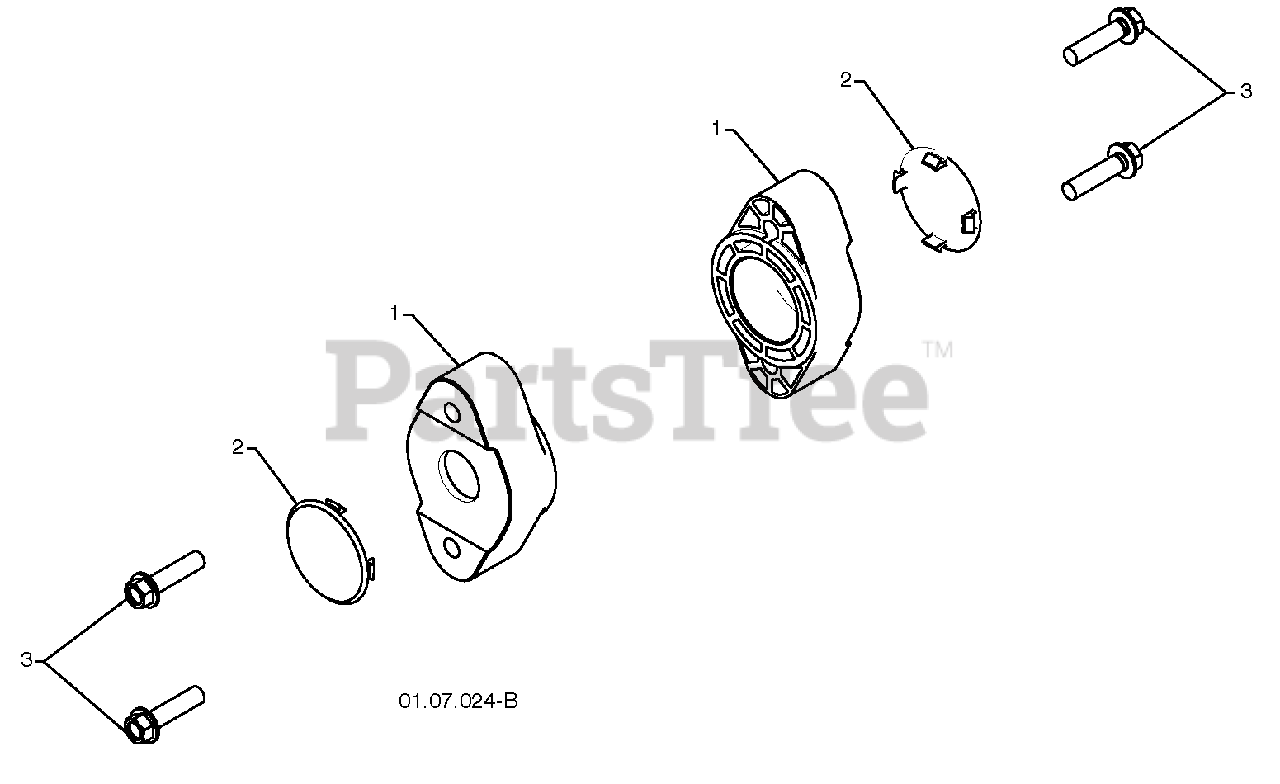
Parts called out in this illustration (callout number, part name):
1	AUGER BEARING
2	BEARING PLUG
3	SCREW 5/16-18 X 1.00
